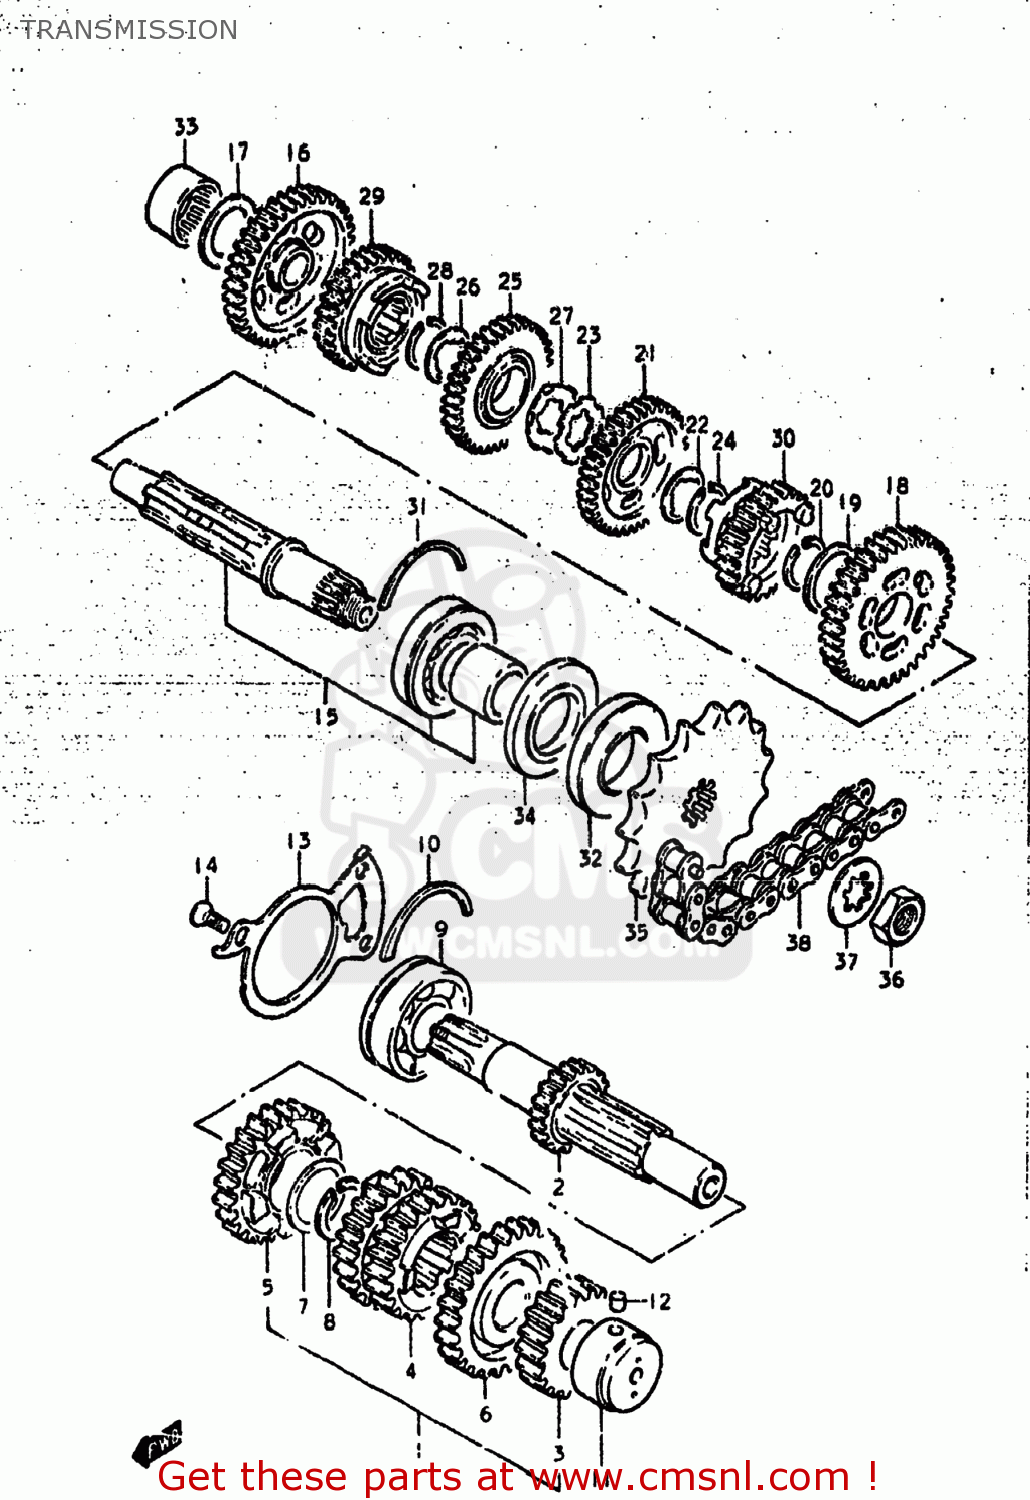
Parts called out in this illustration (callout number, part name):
1	SHAFT,COUNTER
2	SHAFT,COUNTER
3	GEAR,2ND DRIVE(NT:18)
4	GEAR,THIRD DRIVE
5	GEAR,FIFTH DRIVE
6	GEAR,SIXTH DRIVE
7	WASHER
8	CIRCLIP
9	BEARING(25X62X17)
10	C-RING
11	ROLLER BEARING (20X34X2
12	PIN
13	PLATE,COUNTERSHAFT BEARING
14	SCREW
15	SHAFT,DRIVE
16	GEAR,FIRST DRIVEN
17	WASHER
18	GEAR,SECOND DRIVEN
19	WASHER
20	CIRCLIP
21	GEAR,THIRD DRIVEN
22	WASHER,LOCK
23	WASHER,LOCK
24	CIRCLIP
25	GEAR,FOURTH DRIVEN
26	WASHER,LOCK
27	WASHER
28	CIRCLIP
29	GEAR,5TH DRIVEN(NT:25)
30	GEAR,SIXTH DRIVEN
31	C-RING
32	OIL SEAL
33	ROLLER BEARING (20X34X1
34	SEAL,OIL(32X62X5.5)
35	SPROCKET,ENGINE(NT:16)
36	NUT
37	WASHER
38	CHAIN ASSEMBLY,DRIVE
